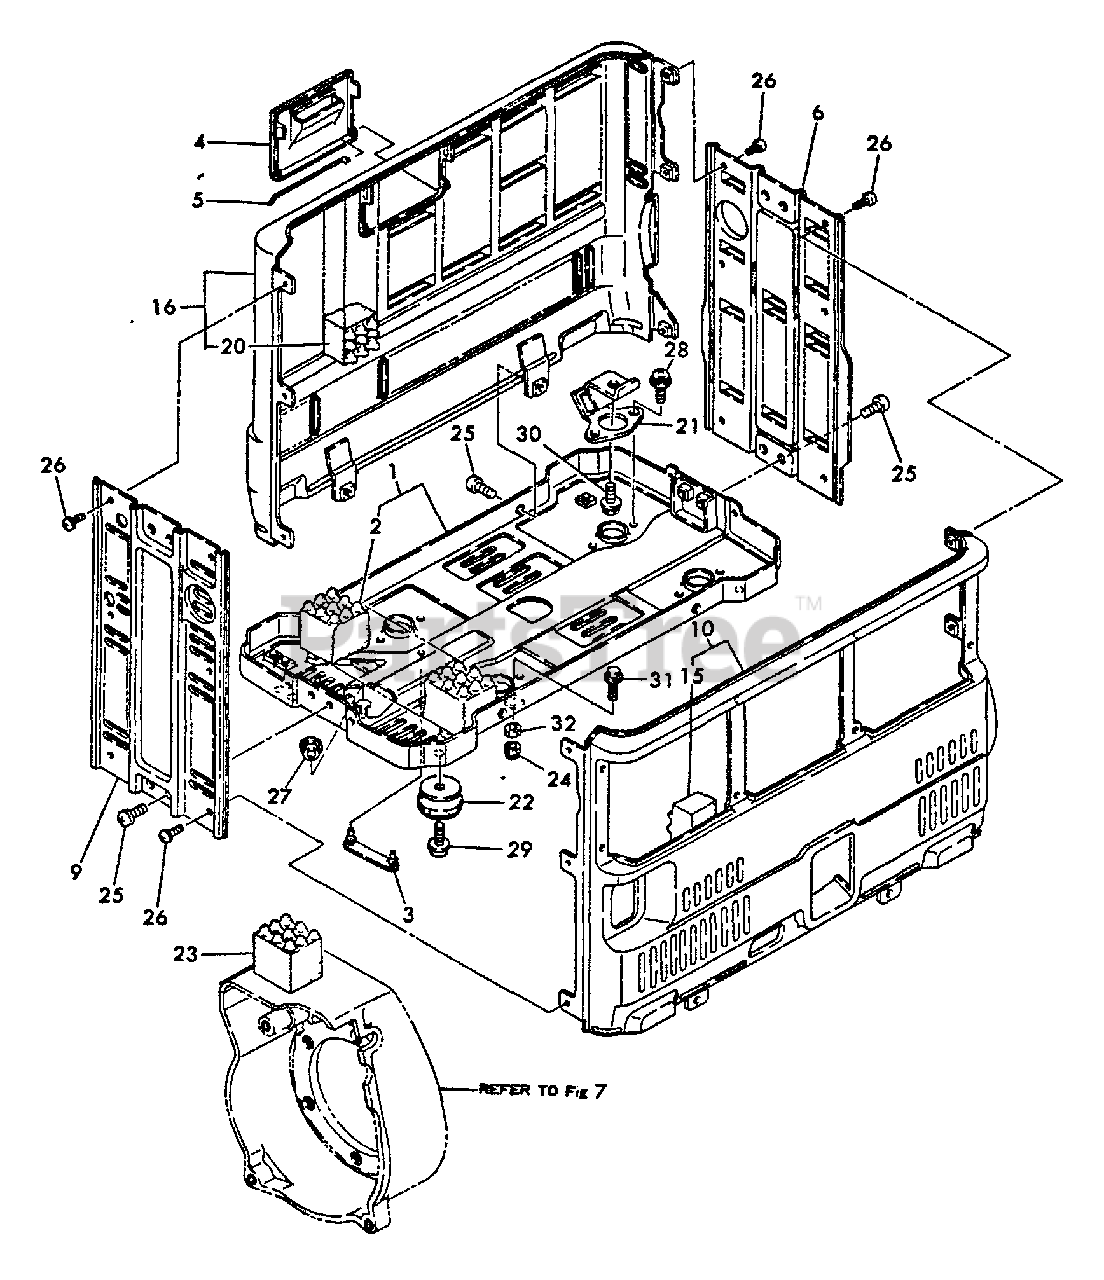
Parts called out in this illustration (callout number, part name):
1	CASE - BOTTOM
2	URETHANE FOAM (E)
3	HOLDER, TOOL
4	PLUG, BLIND
5	SPRING, HINGE
6	SIDE CASE ASSY - RIGHT
9	CASE - LEFT
10	FRONT CASE ASSY
15	URETHANE FOAM (C)
16	GEAR CASE ASSY
20	URETHANE FOAM (D)
21	DAMPER (A)
22	DAMPER (B)
23	URETHANE FOAM (B)
24	NUT
25	SCREW - 6X10
26	SCREW - 4X8
27	GROMMET
28	SCREW - 6X12
29	SCREW - 6X12
30	BOLT - 8X14 -- PLATED
31	BOLT - 6X16 -- PLATED
32	LOCKNUT - 6 -- PLATED
